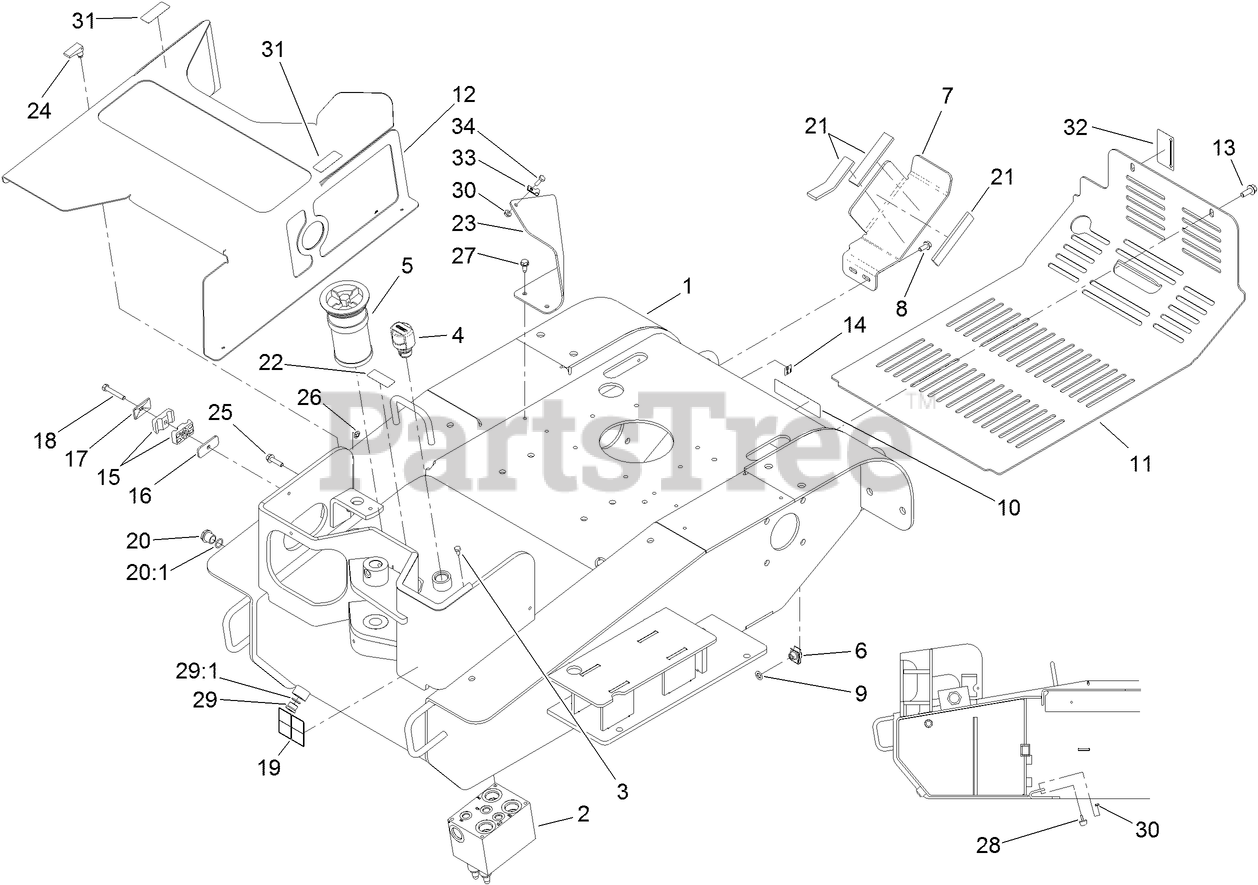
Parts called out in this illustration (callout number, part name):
1	FRAME-MAIN
2	VALVE-CUTTER
3	SCREW-HH
4	BREATHER
5	CARTRIDGE-FILTER
6	NUT-CLIP, U
7	BRACKET-TANK
8	SCREW-HHF
9	NUT-PUSH
10	DECAL-DANGER
11	COVER-REAR
12	COVER-FRONT
13	SCREW-HHF
14	DECAL-POINT, LIFT
15	CLAMP-TUBE
16	PLATE-CLAMP
17	COVERPLATE
18	SCREW-HH
19	DECAL-WARNING
20	SIGHT GLASS ASM
20:1	O-RING
21	PAD-FOAM
22	DECAL-OIL, HYD
23	PLATE-DEFLECTOR, RH
24	LATCH-SWELL
25	SCREW-HHF
26	NUT-PUSH
27	SCREW-HWHTF
28	BUMPER
29	PLUG-HEX
29:1	O-RING
30	NUT-HF
31	DECAL-SURFACE, HOT
32	DECAL-BRAKE, PARKING
33	CLIP-CLOSED, INSULATED
34	SCREW-HH
